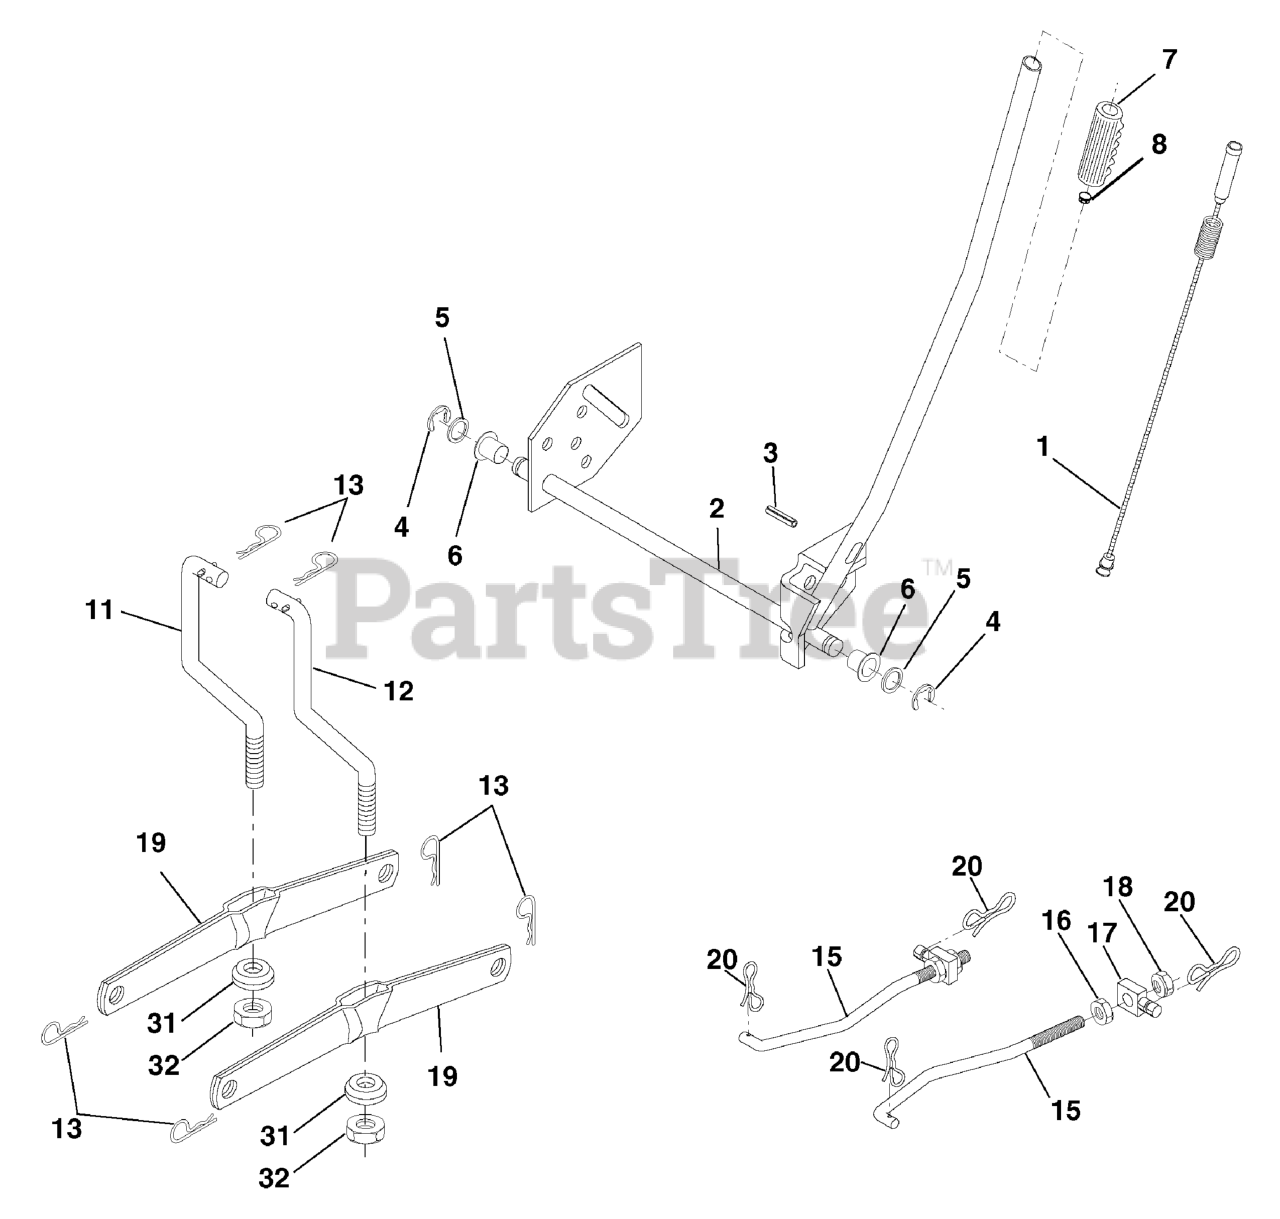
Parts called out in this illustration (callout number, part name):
1	Plunger Asm. Lift LVR
2	Shaft Assembly, Lift
3	Pin, Groove
4	E-Ring
5	Washer 21/32 x 1 x 21 Ga.
6	Bearing, Nylon
7	Grip, Handle
8	Button, Plunger, Red
11	Link, Lift, L.H.
12	Link, Lift, R.H.
13	Retainer Spring
15	Link, Front
16	Nut, Hex, Jam 1/2-13 unc
17	Trunnion
18	Locknut, Hex, with Washer Insert 1/2-13 unc
19	Arm, Suspension, Rear
20	Pin Cotter 7/16 Bow Tie Lock
31	Bearing, Pvt, Lift
32	Nut, Crownlock 3/8-24
